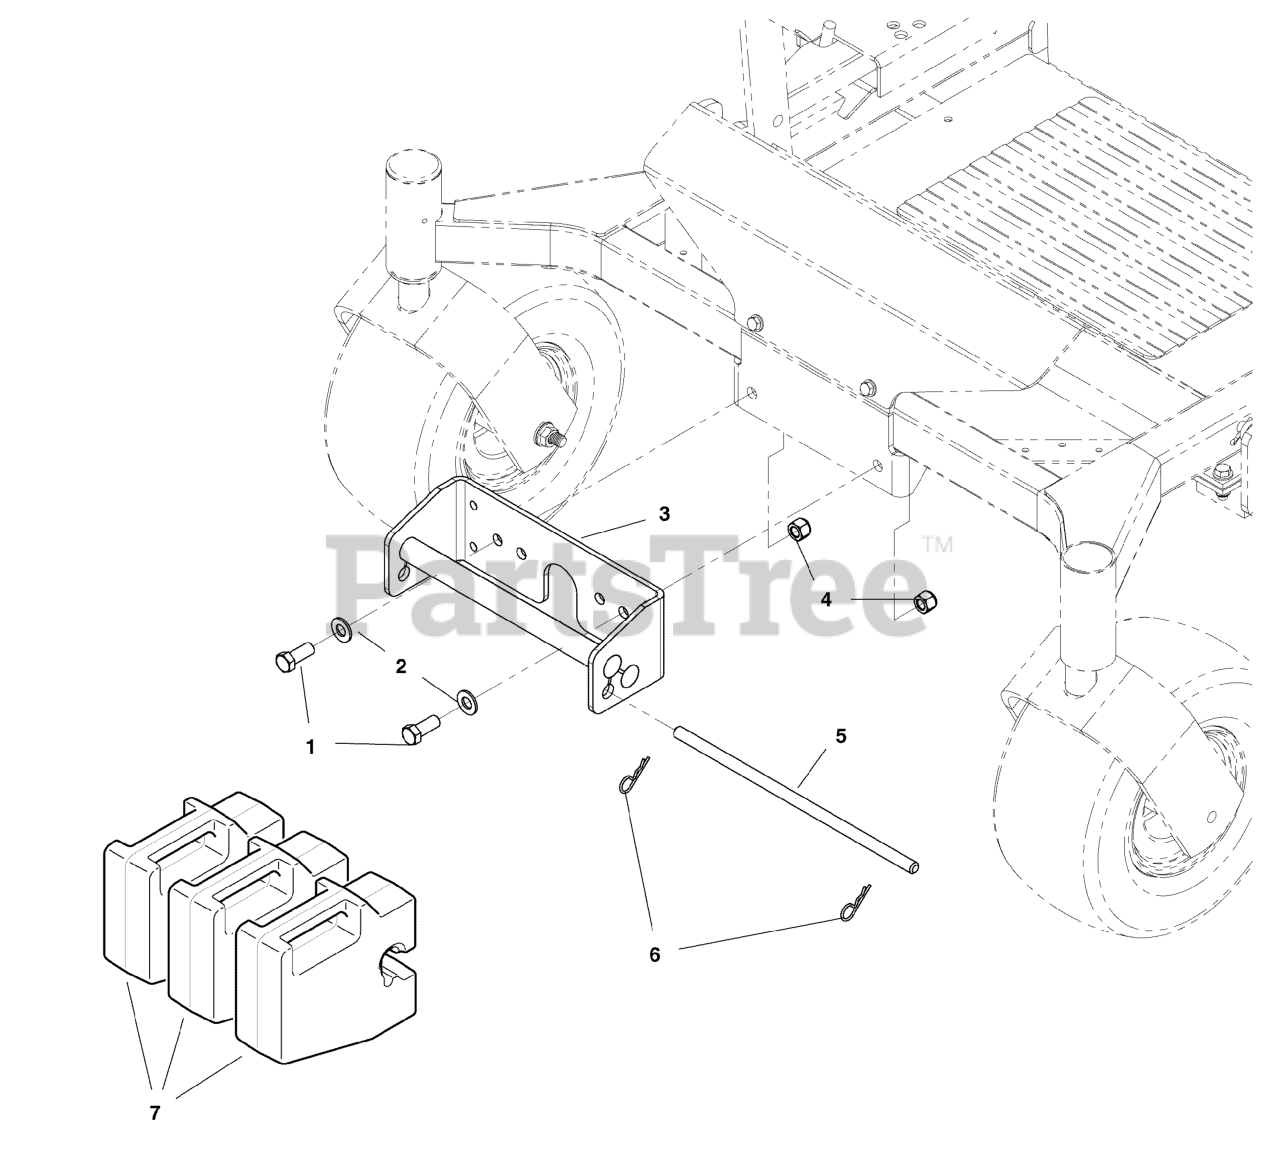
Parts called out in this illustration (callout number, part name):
1	BOLT, 1/2-20 X 1-1/4" GD5 CZ
2	WASHER, 1/2 SAE
3	HOLDER ASMY - WEIGHT
4	NUT, Hex, Nylon Lock, 1/2-20
5	ROD- .500DIA 13.75LG YELLOW
6	PIN, HAIR
7	WEIGHT-QUICK ATTACH 33LBS PAINTED BLACK
7	WEIGHT-QUICK ATTACH 50LB SUITCASE PAINTED
